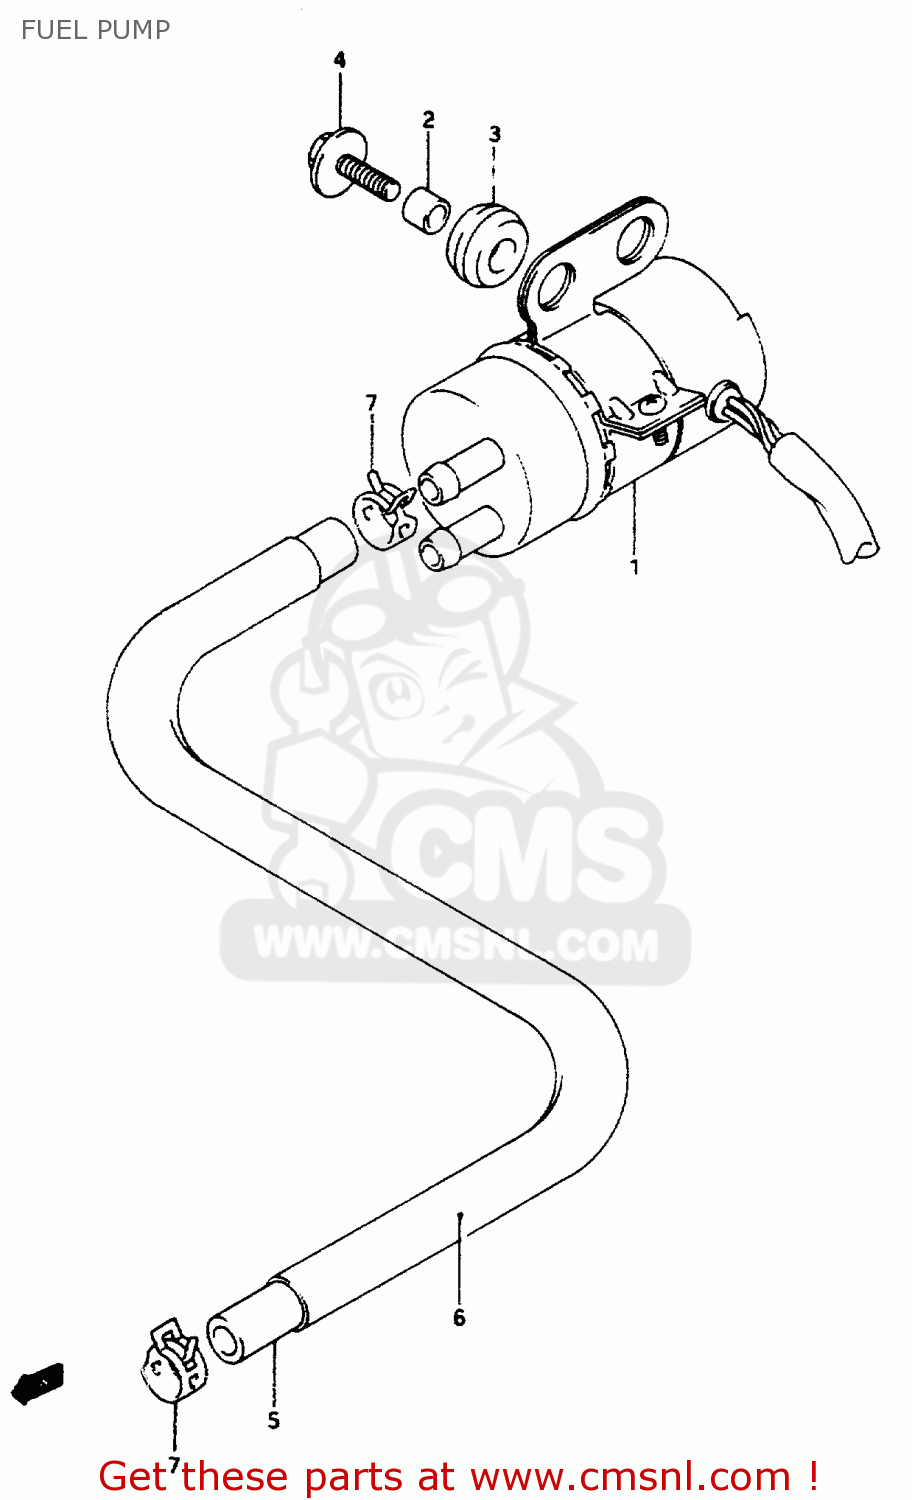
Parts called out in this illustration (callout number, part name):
1	PUMP ASSY,FUEL
2	SPACER(6.5X9X9)
3	CUSHION
4	BOLT(6X20)
5	HOSE(7X12X600)
6	PROTECTOR(14.5X15.5X600)
7	CLIP
